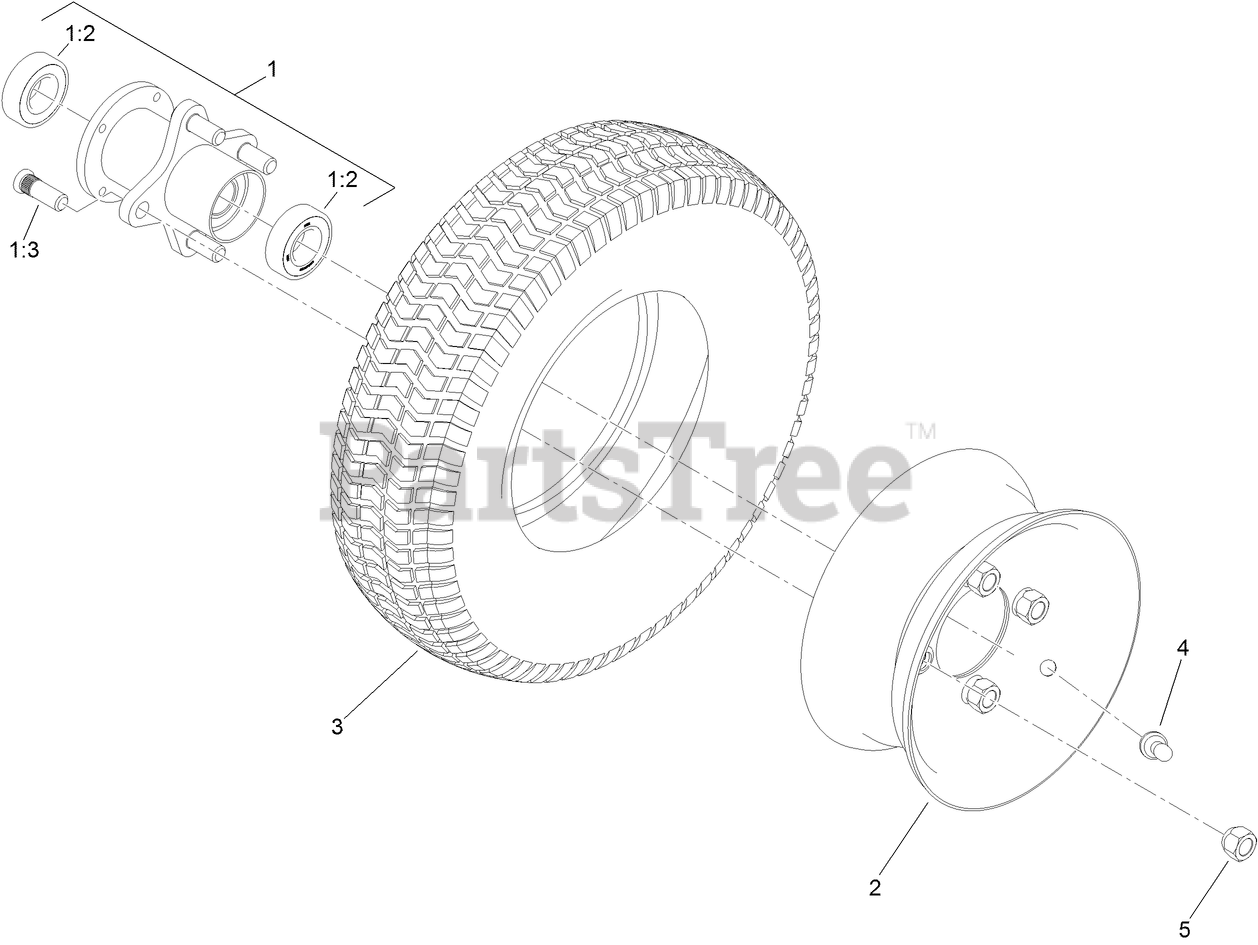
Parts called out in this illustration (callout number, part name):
1	Wheel Hub ASM
1:2	BEARING-BALL
1:3	STUD-WHEEL
2	RIM
3	TIRE
5	NUT-LUG
